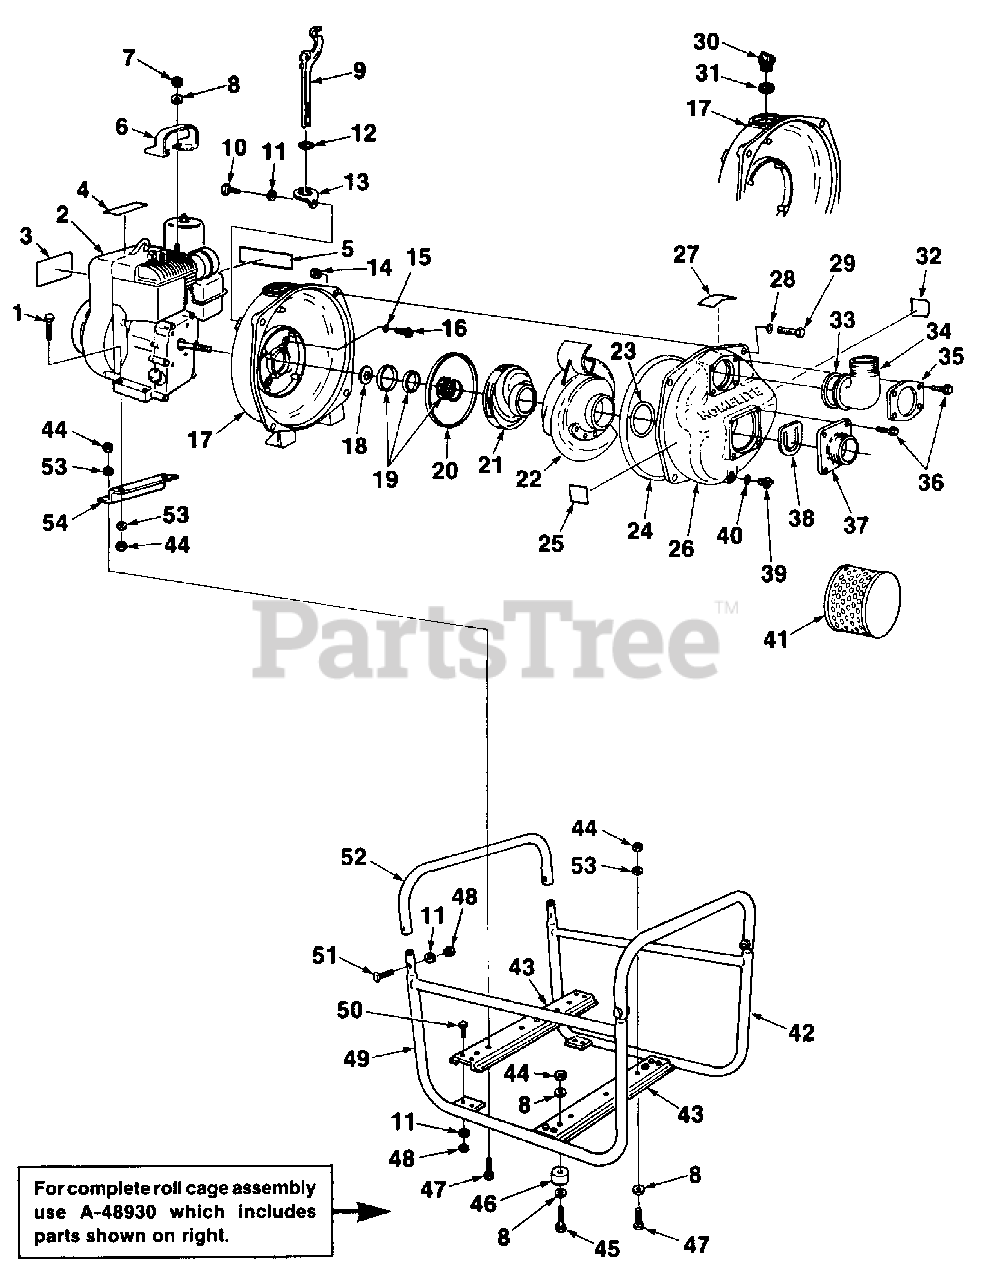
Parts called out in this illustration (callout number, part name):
1	SCREW- Hex cap (5/16-18 x 1 1/2)
4	ENGINE & LABEL (see index #2)
5	DECAL- Homelite
6	HANDLE- Carrying
7	NUT- 5/16-1B
8	WASHER- Flat (5/16)
9	WRENCH
10	SCREW- Tap hex hd (1/4-20 x 3/4)
11	WASHER- Lock 1/4
12	GROMMET
13	BRACKET- Spanner wrench
14	NUT- Hex
15	"O" RING
17	BODY- Pump
18	SLINGER
19	SEAL- Shaft
20	RING- Square
21	IMPELLER
22	DIFFUSER
23	RING- Square
24	"O" RING
26	HOUSING- End
27	LABEL- Warning
28	WASHER- Lock
29	SCREW- Mach hex hd (1/2-13 x 1 1/2)
30	PLUG- Filler assembly
31	GASKET- Wing nut
32	DECAL- Homelite (C-200)
33	"O" RING
34	ELBOW- Discharge 2"
35	CLAMP- Discharge
36	SCREW- Hex hd (5/16-18 x 1)
37	FITTING- Suction 2"
38	VALVE- Check
39	CAP & GASKET
44	NUT- (5/16-18)
53	WASHER- Lock 5/16"
54	SUPPORT- Engine
